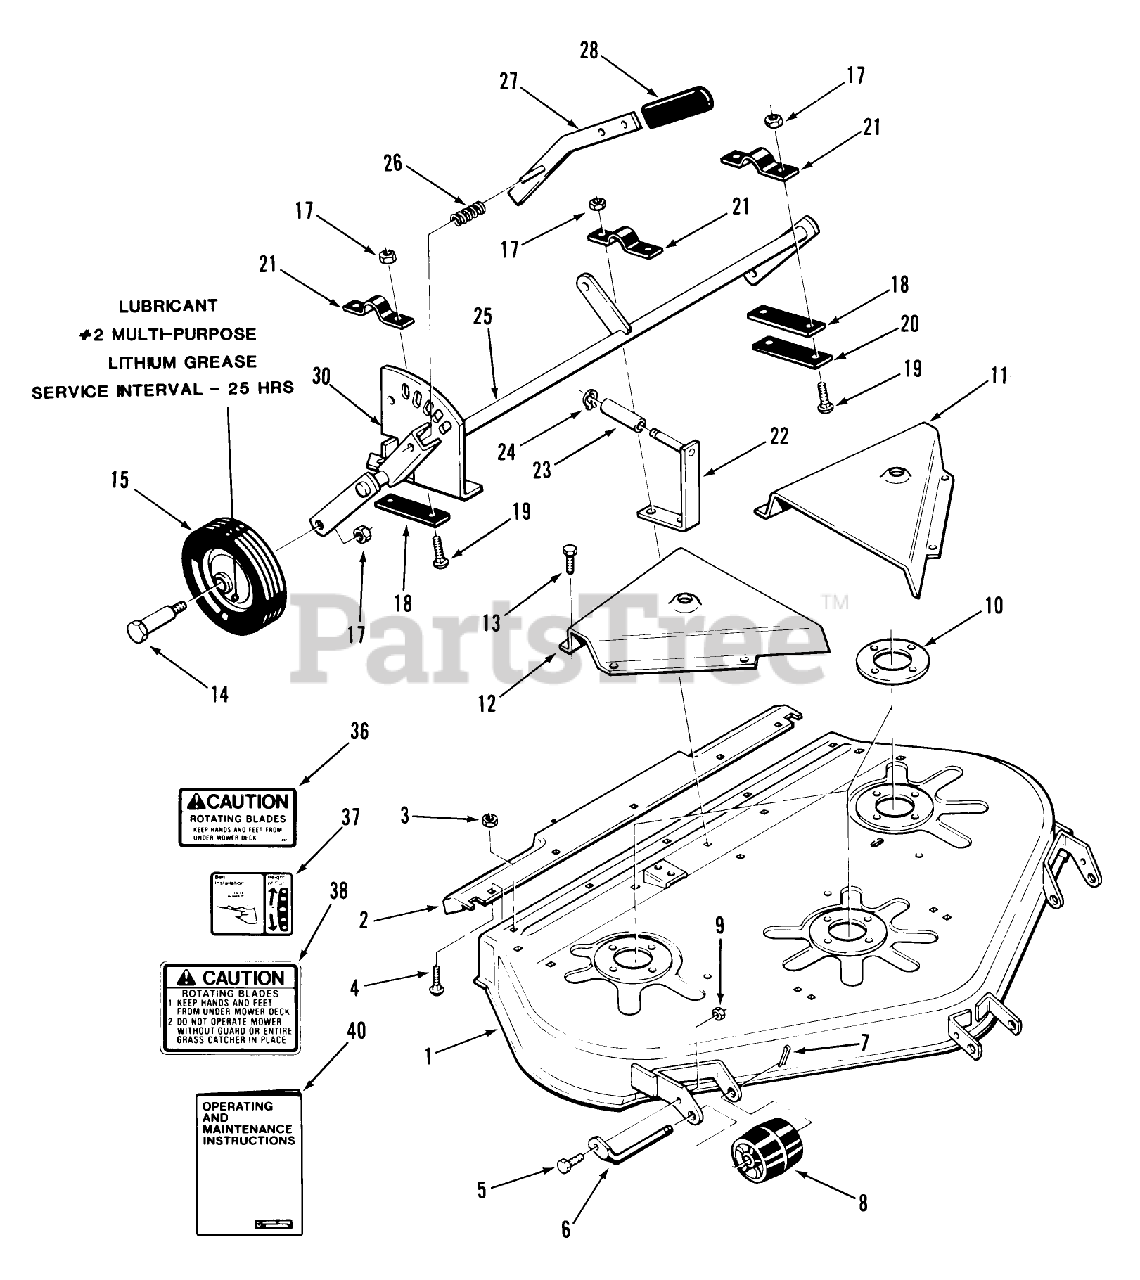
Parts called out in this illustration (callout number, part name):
6	ROLLER-SHAFT
10	PLATE-SPINDLE
13	Bolt
14	BOLT-SHOULDER
15	WHEEL
18	STRAP 1/16 *B
21	CLAMP
26	SPRING-COMPRESSION
37	DECAL-HEIGHT BELT
40	Operating Maintenance Instructions
